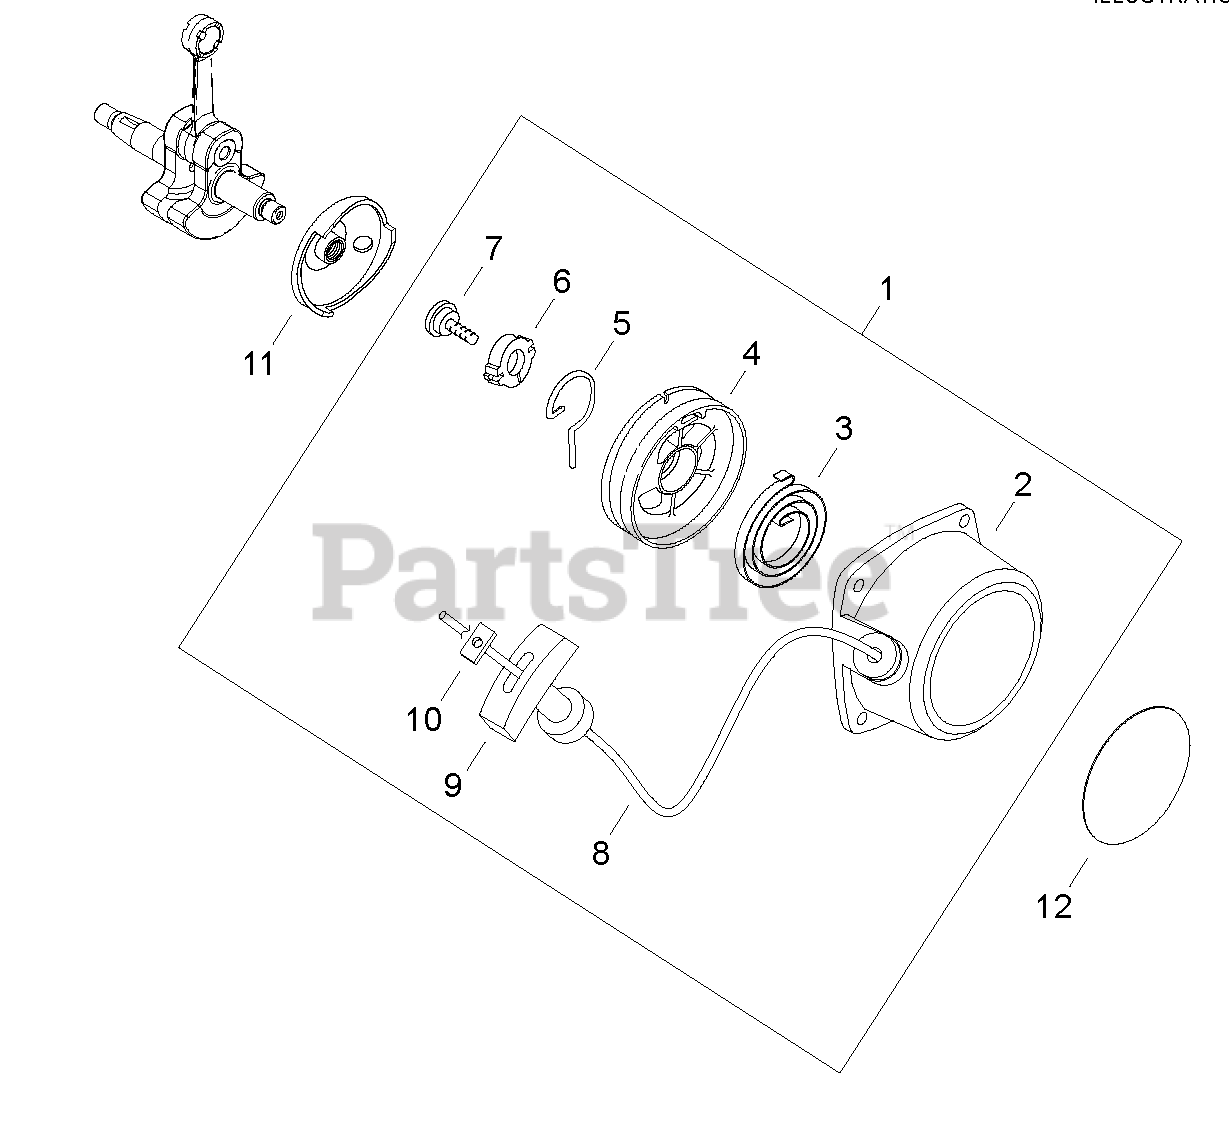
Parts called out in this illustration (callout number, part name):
1	STARTER ASSY, RECOIL
2	CASE, RECOIL STARTER
3	SPRING, RECOIL
4	REEL, ROPE
5	ARM, SWING
6	WASHER 5
7	SCREW 5
8	ROPE, STARTER
9	GRIP, STARTER
10	RETAINER, ROPE
11	PULLEY, STARTER
12	LABEL, C282
